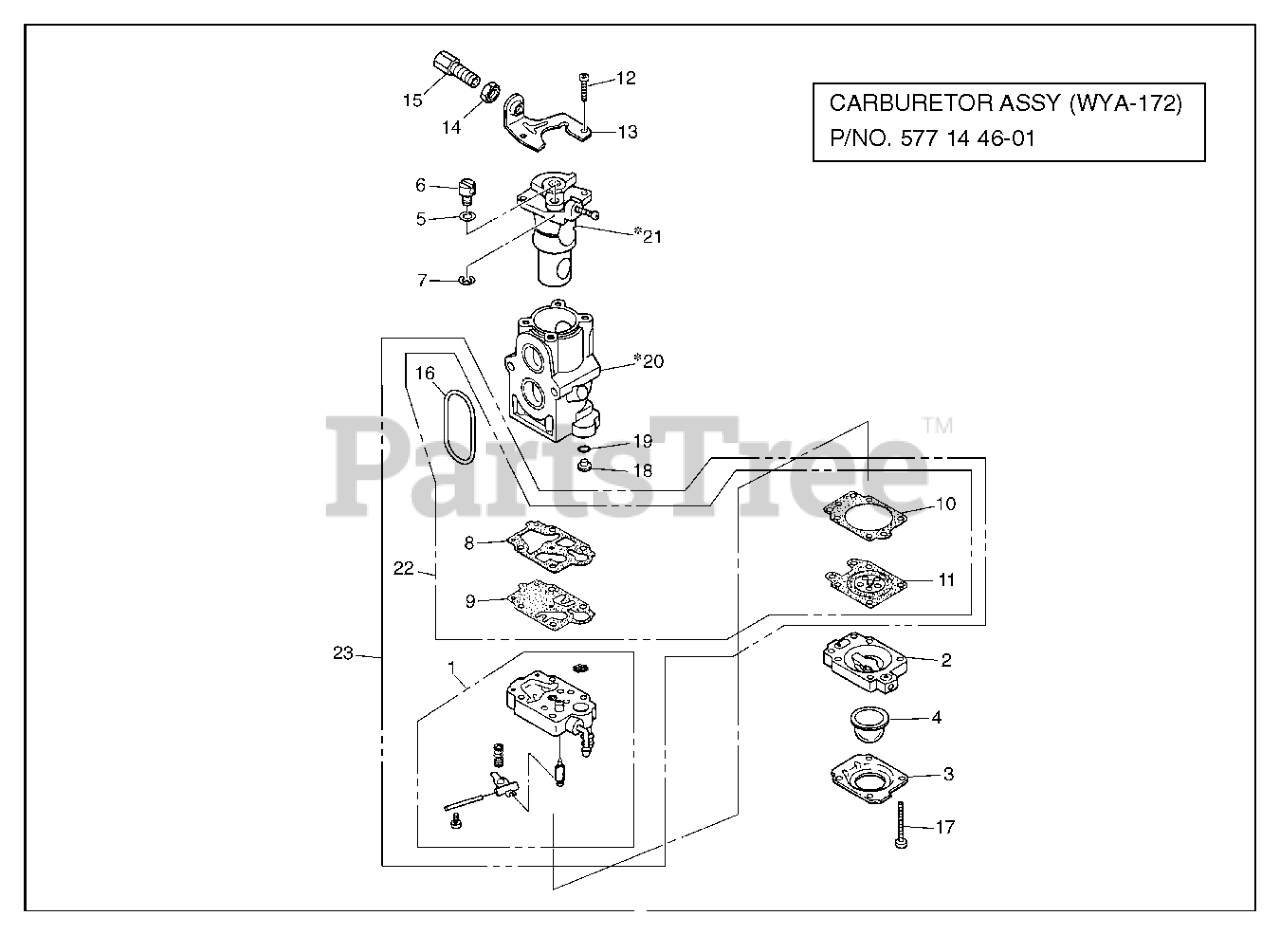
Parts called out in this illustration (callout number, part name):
1	BODY-A-PUMP
3	1OVER
5	WASHER
6	SWIVEL
7	RING
9	DIAPHRAGM
11	DIAPHRAGM
12	SCREW
13	BRACKET
14	NUT
15	ADJUSTER
16	RING
20	CARBURETOR
21	CARBURETOR
22	GASKET KIT
23	REBUILD KIT
